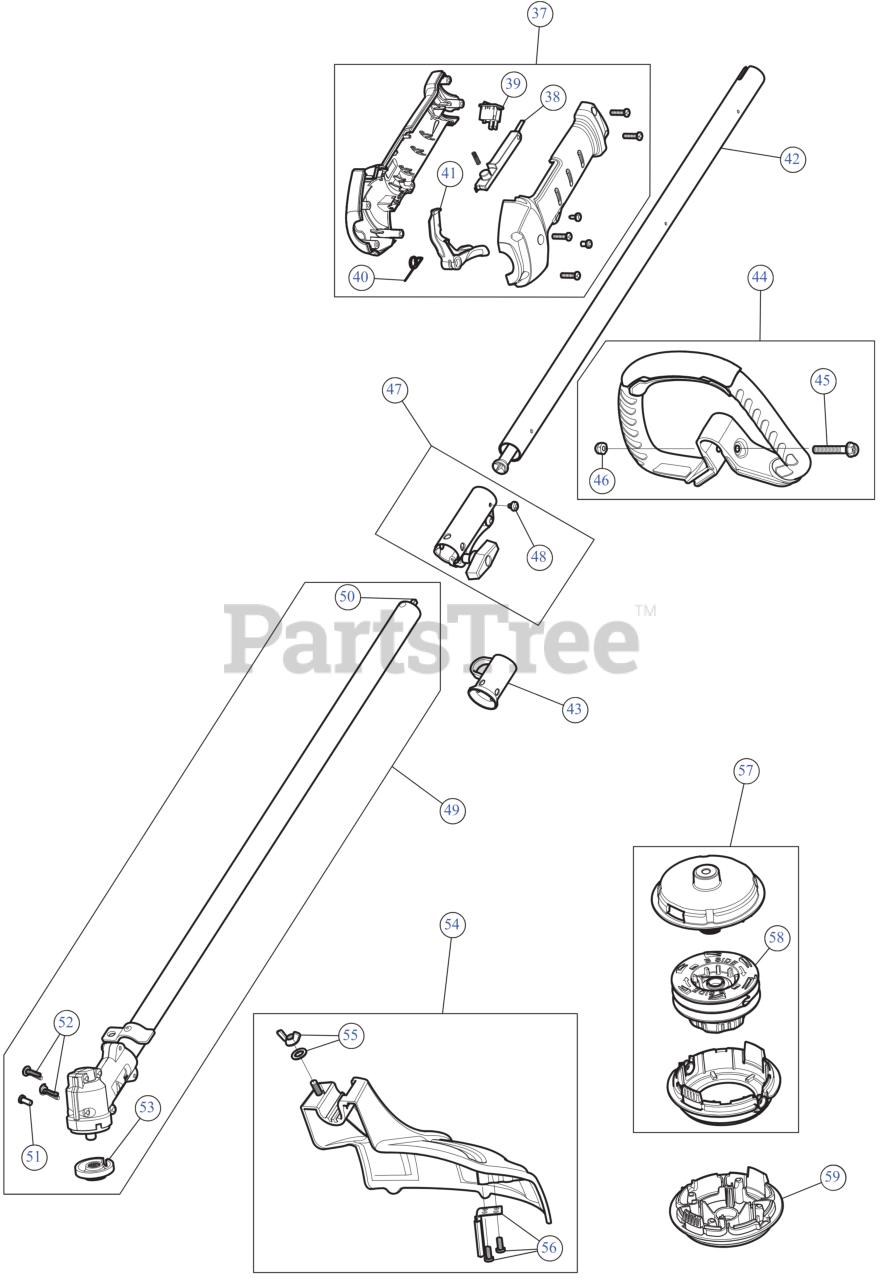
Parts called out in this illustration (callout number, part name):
37	THROTTLE GRIP ASSEMBLY
38	LEVER LOCK OUT
39	SW, MOMENTARY ON/O
40	SPRING TRIG
41	THROTTLE TRIGGER
42	BOOM ASSEMBLY UPR
43	HANGER
44	HANDLE ASSEMBLY
45	BOLT 1/4-20X1 1/2
46	NUT 1/4-20 NYLOC
47	COUPLER ASSEMBLY
48	SCREW, 10-32X.250 TA
49	BOOM (W/GRBX)
50	LOWER DRIVE SHAFT
51	SCREW, 8-32 x .312 P
52	SCREW #
53	CUTTING HEAD SPACER
54	GUARD/BLADE ASM
55	BLADE GUARD MOUNTING HARDWARE
56	BLADE ASSEMBLY W/HDW
57	COMPLETE HEAD ASSEMBLY
58	BUMP KNOB
59	CAP ASSEMBLY W/PLUG
